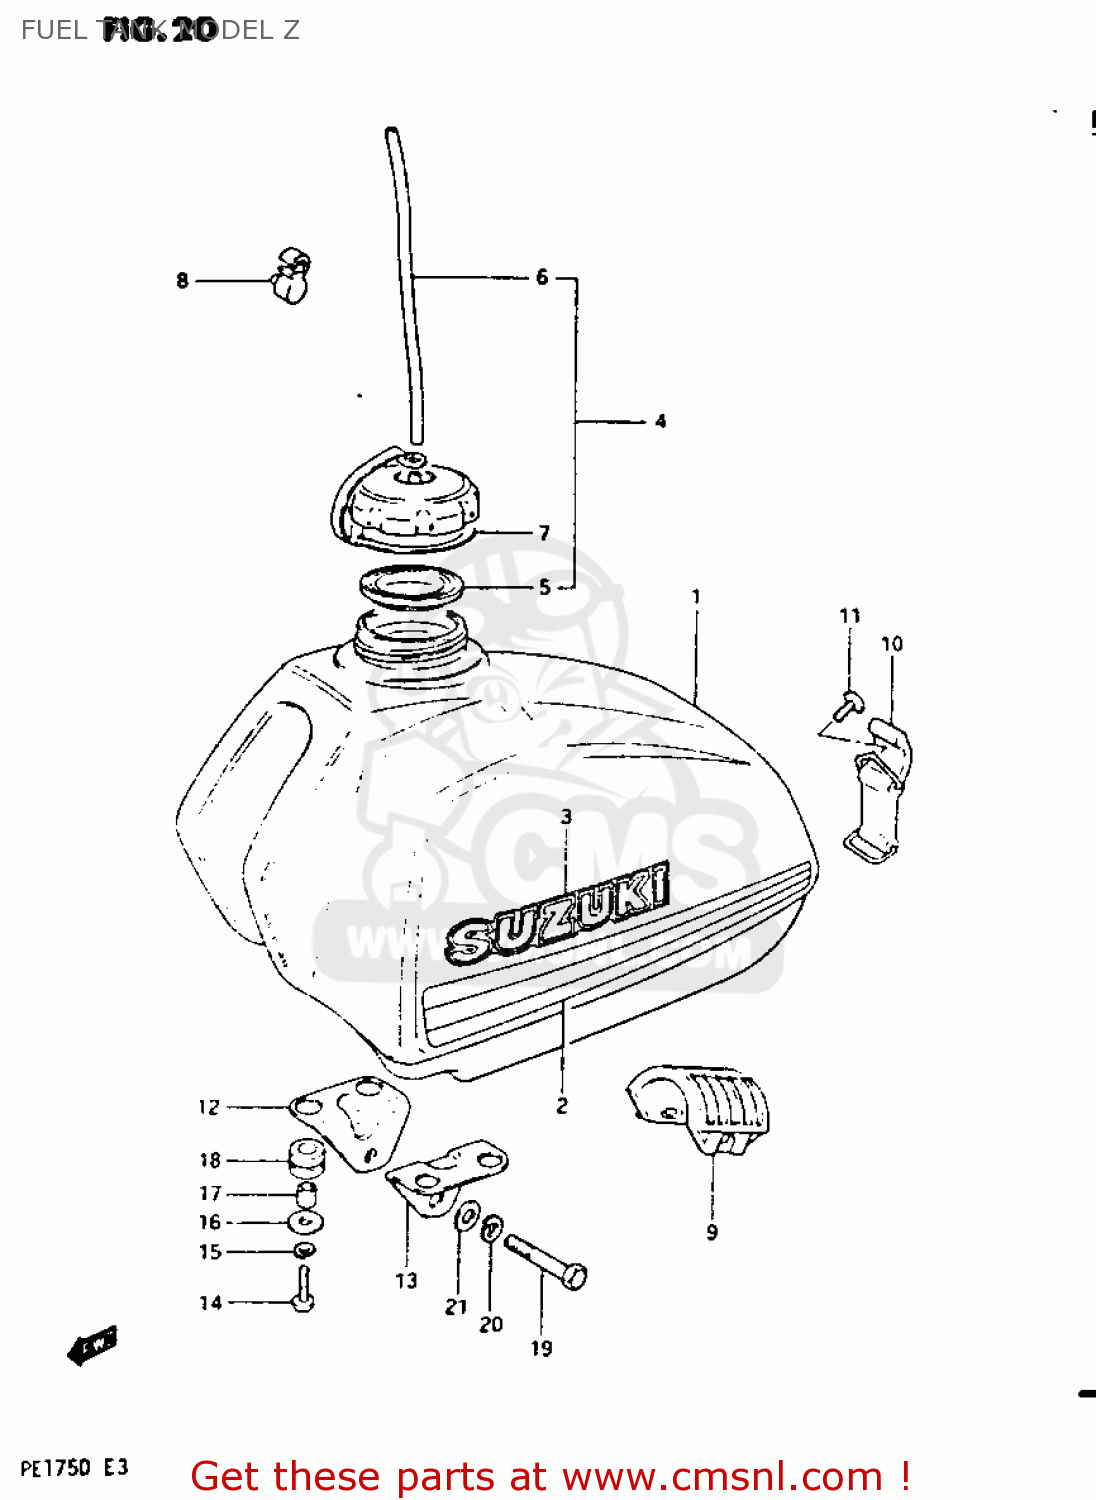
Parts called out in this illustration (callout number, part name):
1	TANK ASSEMBLY,FUEL
2	TAPE SET,FUEL TANK
3	EMBLEM
4	CAP,FUEL TANK
5	GASKET,FUEL TANK CAP (NAS)
6	HOSE
7	BAND,FUEL TANK CAP
8	CLAMP,BREATHER HOSE
9	CUSHION,FUEL TANK
10	BAND,FUEL TANK,REAR
11	SCREW(6X18)
12	BRACKET,FUEL TANK,LOWER
13	BRACKET,FUEL TANK
14	SCREW
15	WASHER,LOCK
16	WASHER (6.5X24X1.6)
17	SPACER(6.8X12X11)
18	CUSHION
19	HEXAGON BOLT 8X80
20	LOCK WASHER
21	WASHER
